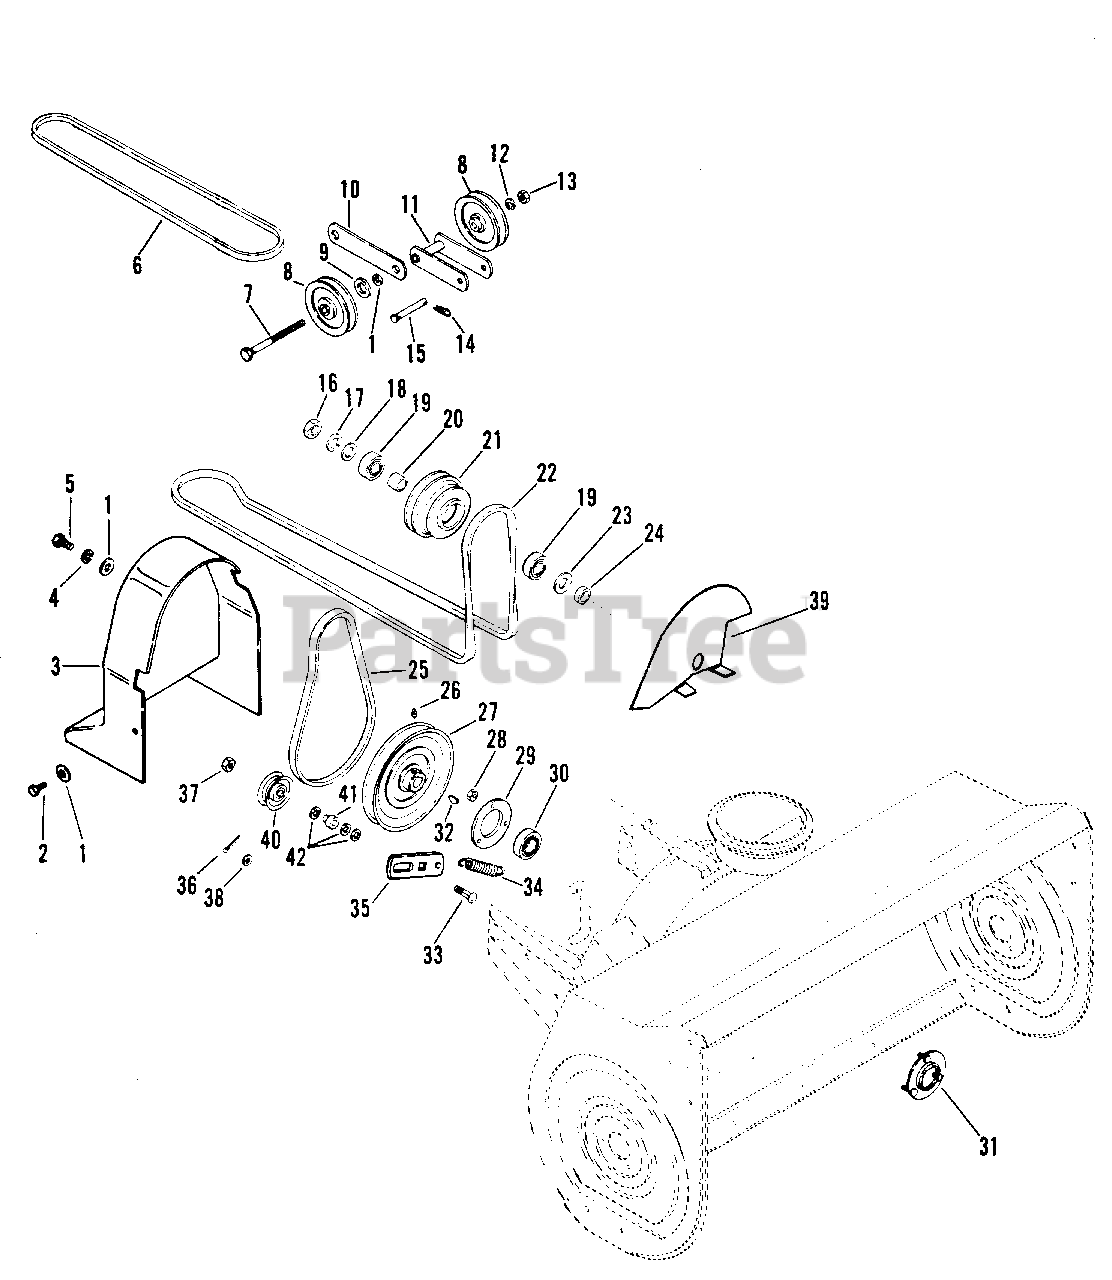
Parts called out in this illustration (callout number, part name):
1	Washer, Flat .406x.812x.065
2	Taptite, 5/16-18x.50
3	Guard, Belt
4	Washer, Lock 5/16 SP
5	Bolt, Hex 5/16-18x.75
6	Belt
7	Bolt, Hex 3/8-16x5.00
8	Idler, .375x4
9	Washer, Flat .813x1.37x.100
10	Strap
11	Bracket, Idler
12	Washer, Lock 3/8 Reg.
13	Nut, Hex 3/8-16
14	Hairpin, Internal
15	Pin, Clevis
16	Nut, Jam 3/4-10 Hex
17	Lockwasher, Internal .75 I.D.
18	Washer, .770x1.250x06
19	Bearing, Radial
20	Spacer
21	Sheave
22	V-Belt, .5x109" 4L
23	Washer, .774/.811x1.500x.187
24	Spacer
25	V-Belt
26	Screw, Set
27	Sheave, .625x7.50
28	Nut, Lock 1/4-20
29	Bearing, Flange
30	Bearing, Radial
31	Bearing, Flange
32	Key, Wdrff .187x.875 HRD #11
33	Bolt, 3/8-16x1.50 Rd Hd Sq Nk
34	Spring, Ext. 3-1/2 Free Length
35	Arm, Idler
36	Pin, Cotter .125x.75
37	Nut, Lock 3/8-16
38	Washer
39	Shield
41	Spacer
42	Washer, Flat .531x1.062x.095
